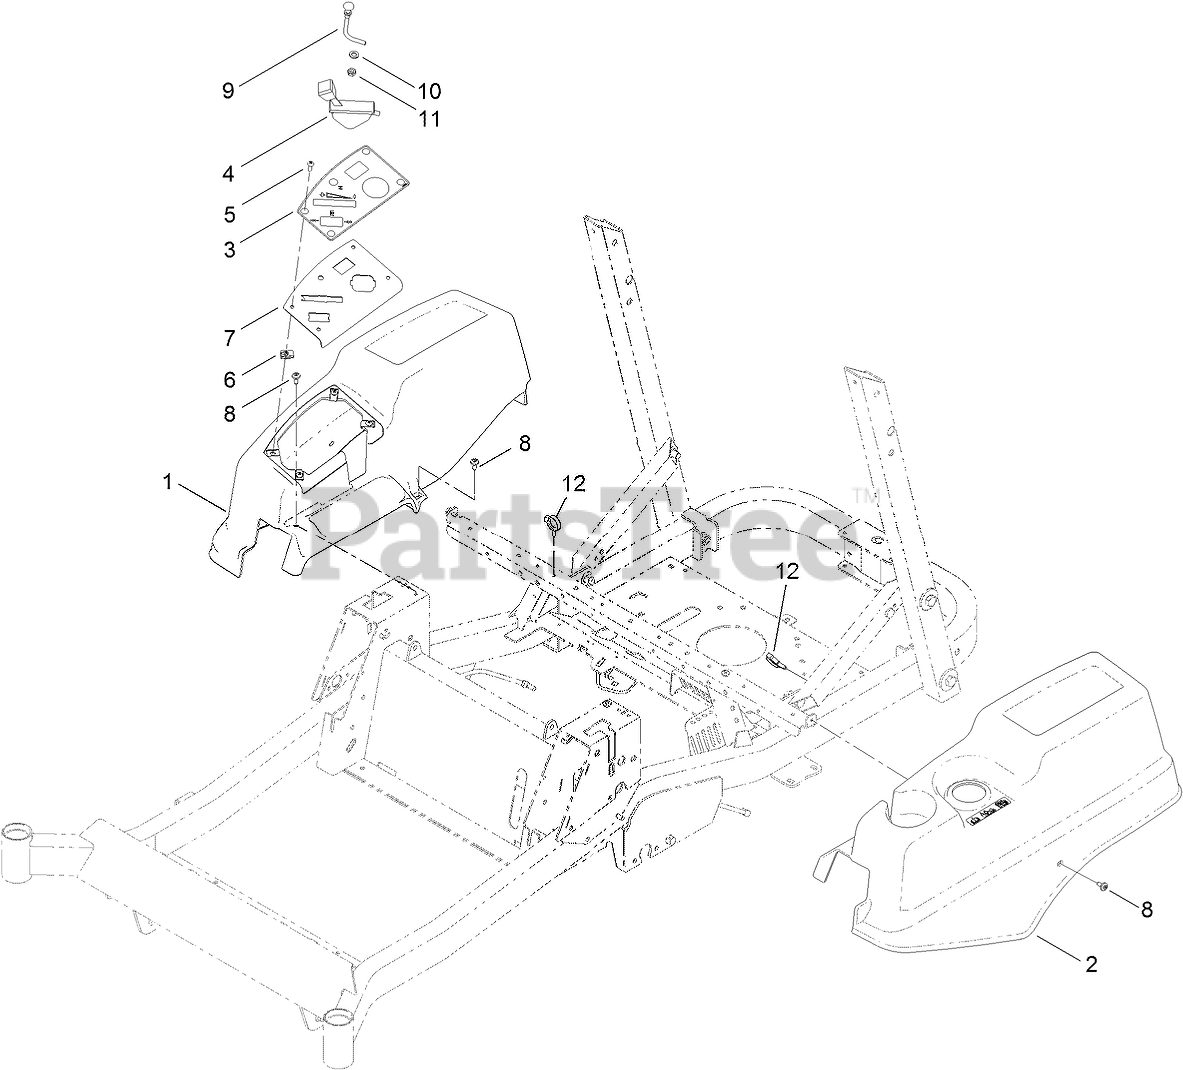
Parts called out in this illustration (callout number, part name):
1	POD-RH
2	POD-LH
3	DECAL-PANEL, CONTROL
4	CABLE-THROTTLE
5	SCREW-PRH
7	PANEL-CONTROL
8	SCREW-SHOULDER
9	CABLE-CHOKE
10	WASHER-LOCK
11	NUT-HJ
12	CLAMP-HOSE
